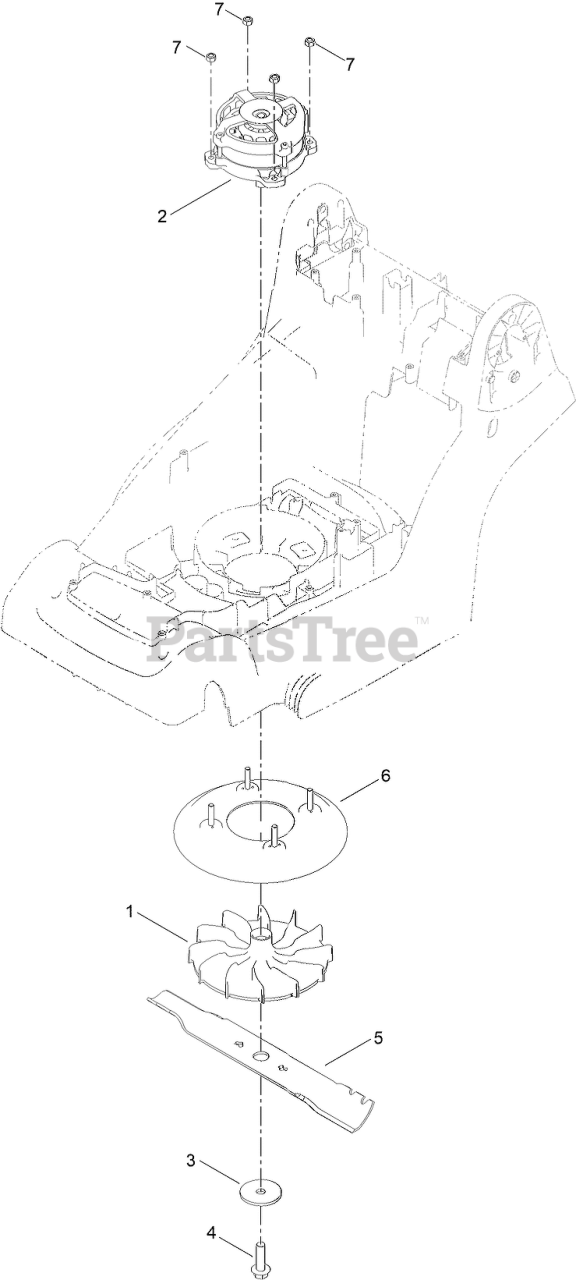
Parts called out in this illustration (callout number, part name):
1	BLADE CARRIER
2	MOTOR, BRUSHLESS, 60V, 600W
3	BLADE WASHER
4	BLADE BOLT
5	BLADE, MULCH, 36CM
6	BLADE COVER
7	NUT, NYLOC, M6X1
